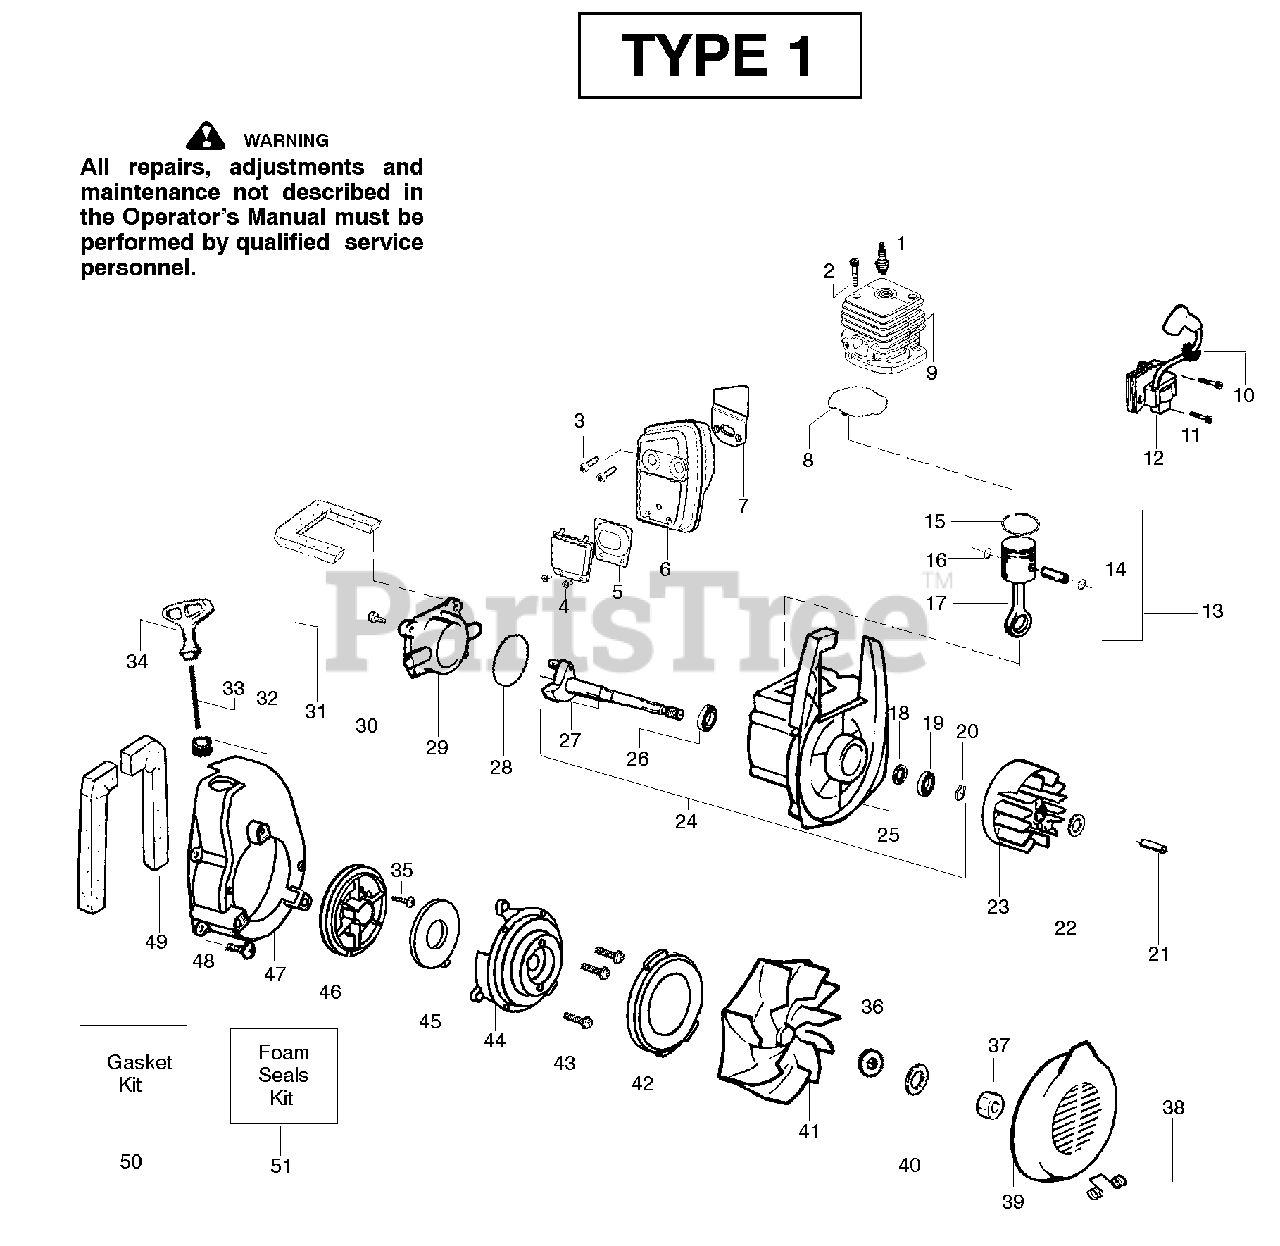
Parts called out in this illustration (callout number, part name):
1	Spark Plug (RCJ-6Y)
3	Screw-Muffler-Internal
5	Kit-Spark Screen
6	Kit-Muffler
7	Gasket-Baffle (kit)
8	Gasket-Cylinder (kit)
9	Kit-Cylinder
10	Grommet-Ign. Module
11	Screw-Ignition Module
12	Ignition Module
13	Kit-Piston/Rod
14	Kit-Piston
15	Piston Ring
16	Retainer-Piston Pin
17	Assy-Connecting Rod
18	Seal-Crankcase
19	Bearing-Outer
20	Retainer Ring-C'chaft
21	Spacer-Flywheel
23	Assy-Flywheel
24	Assy-Crankcase/Crank shaft
25	Assy-Crankcase
26	Bearing-Inner
27	Assy-Crankshaft
28	O-ring-C/case (kit)
29	Cover-Crankcase
30	Screw
31	Foam-219mm (kit)
32	Eyelet-Flange
33	Kit-Rope
34	Handle-Starter
35	Screw-Rope
36	Washer-Belleville
38	Spring-Return Cover
39	Inlet Door
41	Assy-Impeller
42	Seal-Ring
44	Housing-Pulley
45	Spring-Starter
46	Kit-Starter Pulley
47	Fan Housing
48	Screw
49	Foam-182mm (kit)
50	Kit-Gasket
51	Kit-Foam Seals
